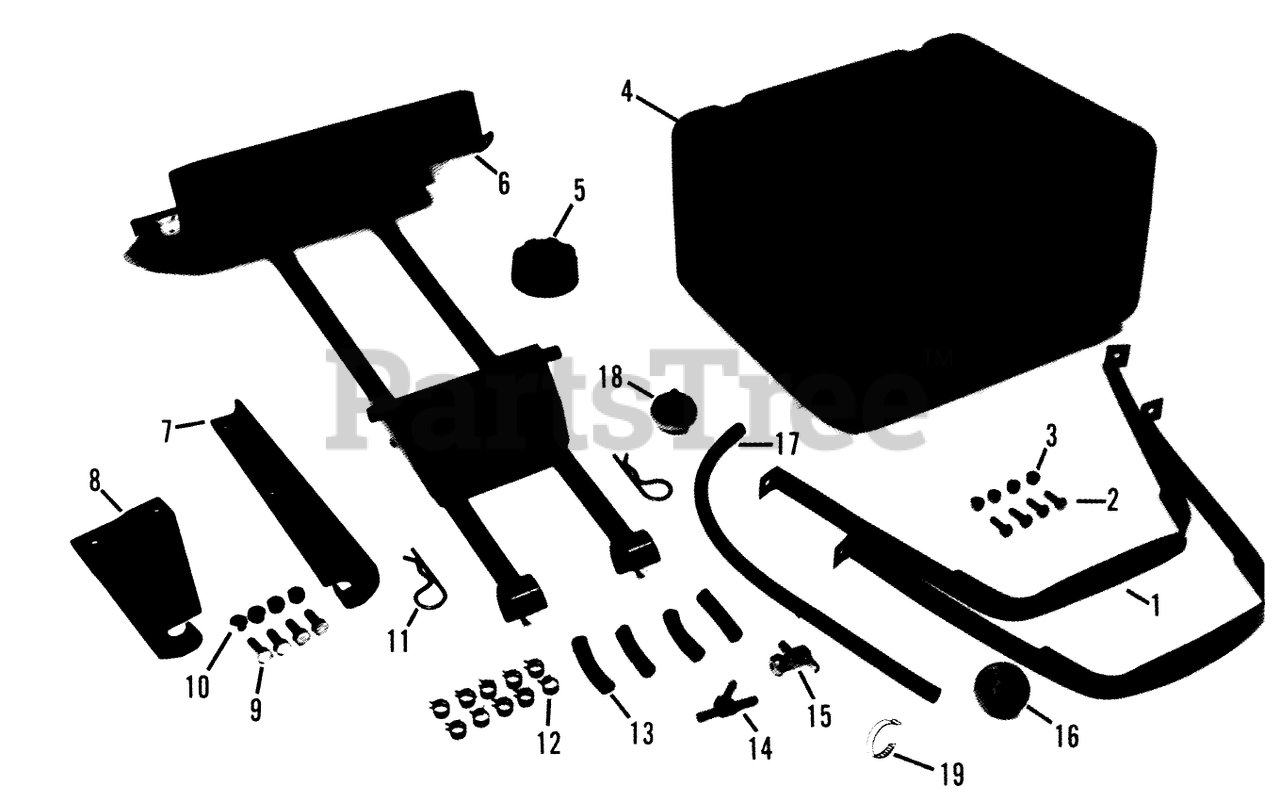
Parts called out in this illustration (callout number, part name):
1	Strap
2	H H C S
3	Nut
4	Fuel Tank
5	Tank Cap
6	Frame
7	SUPPORT-BAGGER R. B
8	SUPPORT-BAGGER L. B
9	HHCS
10	Nut
11	Hairpin
12	CLAMP
13	Fuel Hose-2" Long
14	FITTING-FUEL 45-Y
15	Fuel Shut-off Valve
16	VALVE-CHECK
17	Skid Bracket
18	FILTER-FUEL
19	PLASTIC TIE
